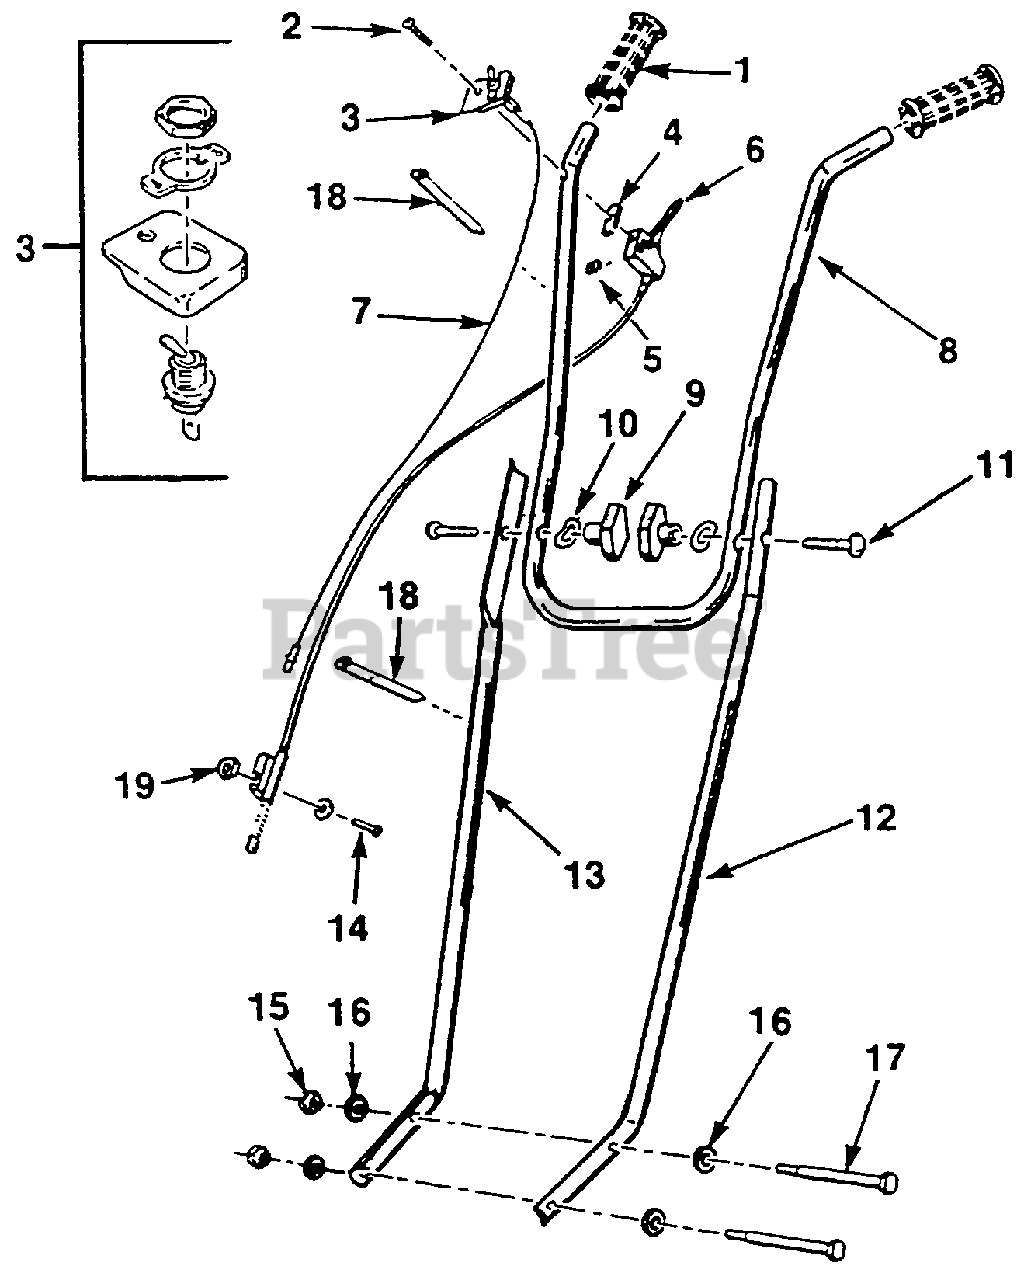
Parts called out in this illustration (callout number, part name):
1	GRIP- Handlebar
2	SCREW- Set (#10-24 x 1 3/8")
3	SWITCH ASSEMBLY-w/Mounting Plate
4	ISOLATOR- Trigger
5	NUT- Throttle/Switch Assy.
6	THROTTLE CABLE ASSEMBLY w/Throttle Trigger
7	GROUND WIRE ASSEMBLY
8	HANDLEBAR- Upper
9	KNOB- Plastic Handlebar (5/16")
10	WASHER- Curved Knob (5/16")
11	SCREW- Curved Head (5/16-18 x 1 1/2")
12	HANDLEBAR- Lower (L.H.)
13	HANDLEBAR- Lower (R.H.)
14	SCREW- Hex hd. (#8-32 x 1")
15	NUT- Flex-lock (1/4-20)
16	WASHER- Curved (5/16")
17	SCREW (1/4-20 x 4 1/2")
18	TIE STRAP
19	NUT- Hex (8-32)
